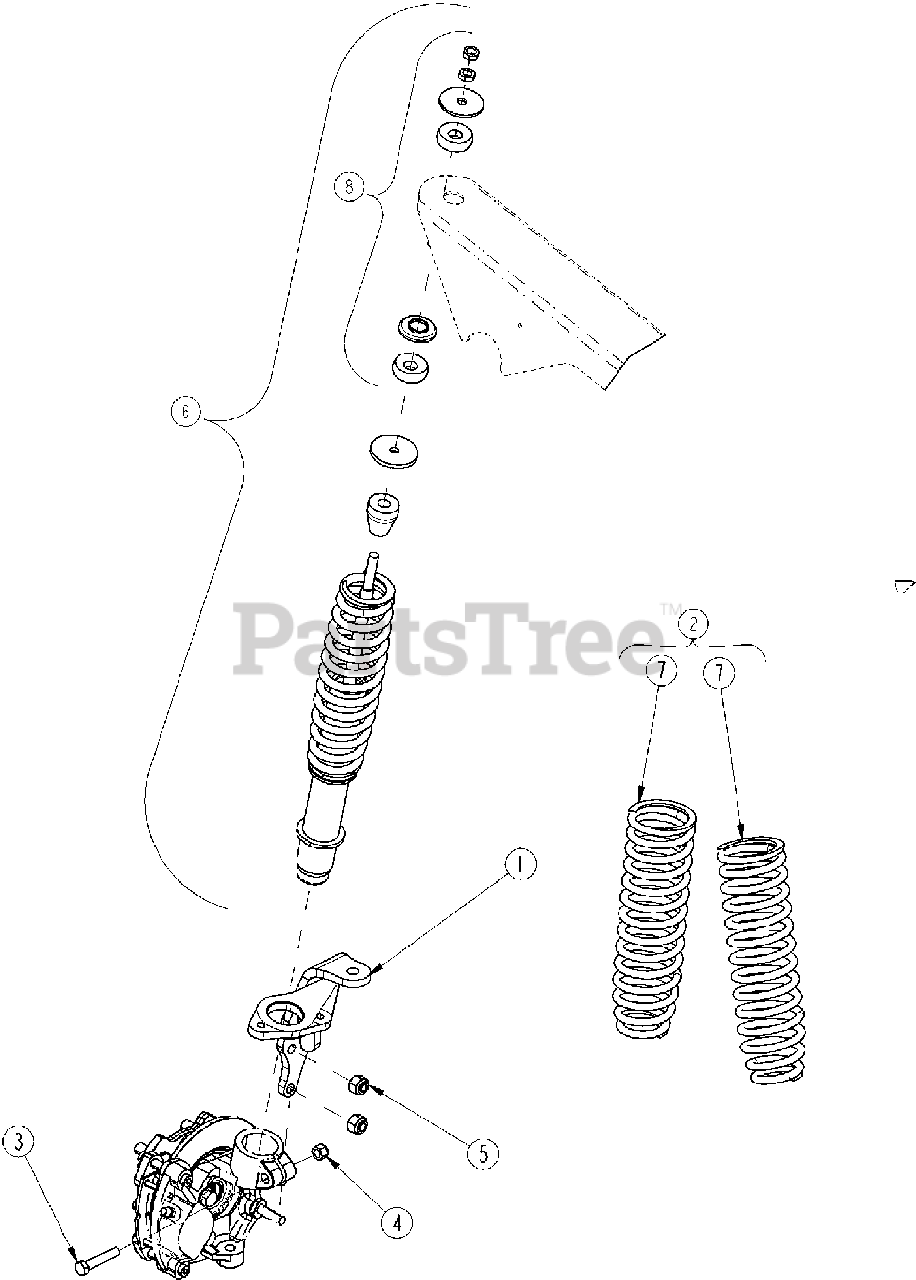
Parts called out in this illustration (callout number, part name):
1	STEERING BRACKET RIGHT
1	STEERING BRACKET LEFT
2	SPRINGS, ST TRUCK HI RATE 2 ea. Item 7
3	BOLT, HEX 3/8-16 X 2.00 GR8 PLT
4	NUT, LOCK 3/8-16 NYLON INSERT
5	NUT HEX NYLOCK M10X1.5 PLT
6	SHOCK COIL/STRUT FRNT TRUCK
7	SPRG, TRUCK FRT STRUT HI RATE
8	STRUT TOP HARDWARE KIT
